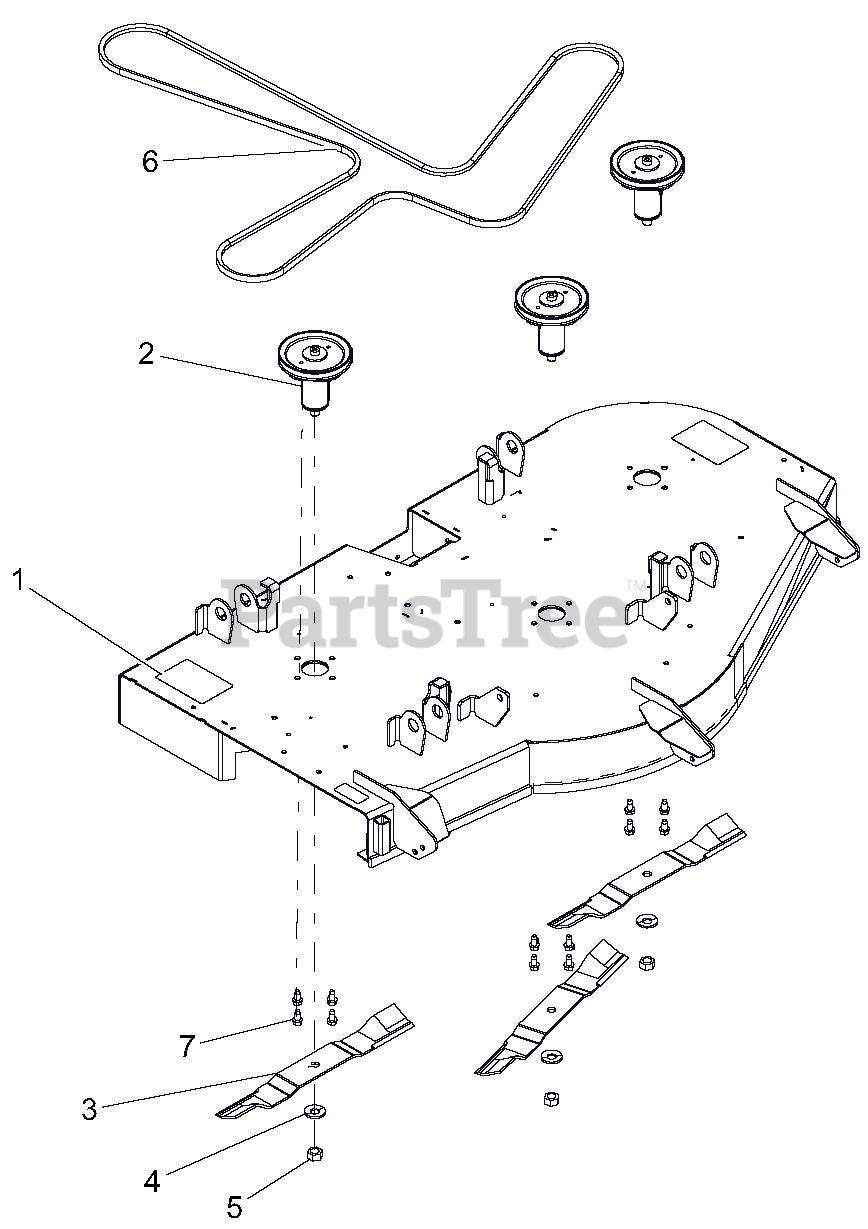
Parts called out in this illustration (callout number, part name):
1	KIT, 52" ARIENS DECK W/DECALS
2	KIT, DECK SPINDLE ASM-52
3	BLADE, 18" - 30 DEG .5 OFFSET
4	WSHR-BLVL .669X1.535X.138
5	NUT-HEX .62-18 YWZC
6	V-BELT, HA-WRAPPED
7	@SCR-TAP .38-16X.75 HWH TR YWZ
